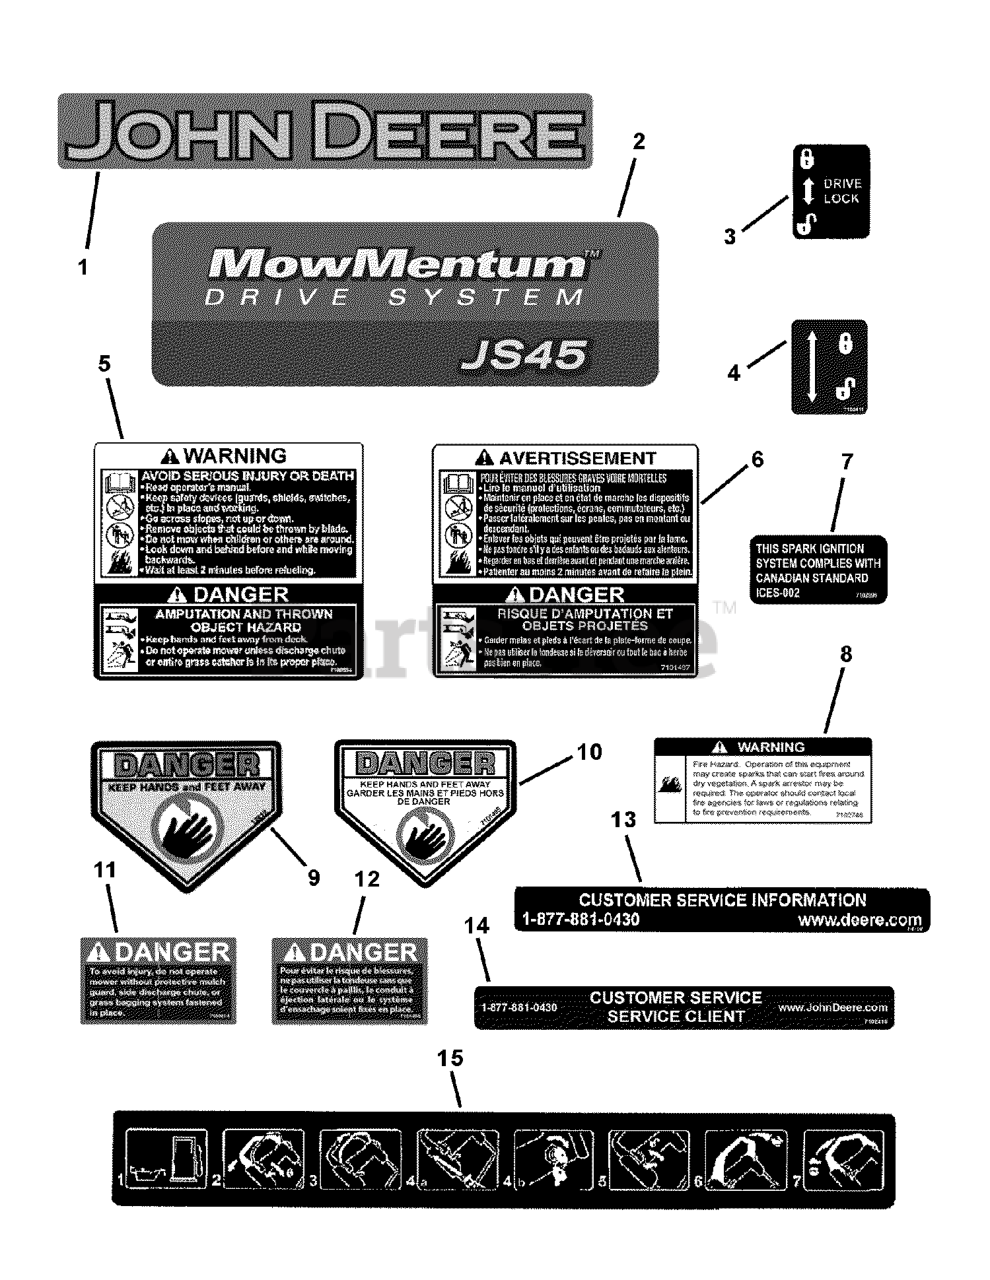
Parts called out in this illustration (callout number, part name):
1	DECAL, JD SWIVEL WHEEL, JS40
2	DECAL, MOWMENTUM, JS45
3	DECAL, NEUTRAL LOCK
4	DECAL, NEUTRAL LOCK, FC
5	DECAL, WARNING/DANGER WBM
6	DECAL, WARNING/DANGER,FRENCH/ENGLISH
7	DECAL, COMPLIANCE, ICES
8	DECAL, ARRESTOR, SPARK
9	DECAL, DANGER, CUT FINGER
10	DECAL, CPSC, FRENCH/ENGLISH
11	LABEL, DANGER - DEERE
12	DECAL, DANGER, FRENCH
13	DECAL, CUSTOMER SERVICE, MY08, DEERE
14	DECAL, CUSTOMER SERVICE, DEERE, FRENCH
15	DECAL, OPERATION, JD
